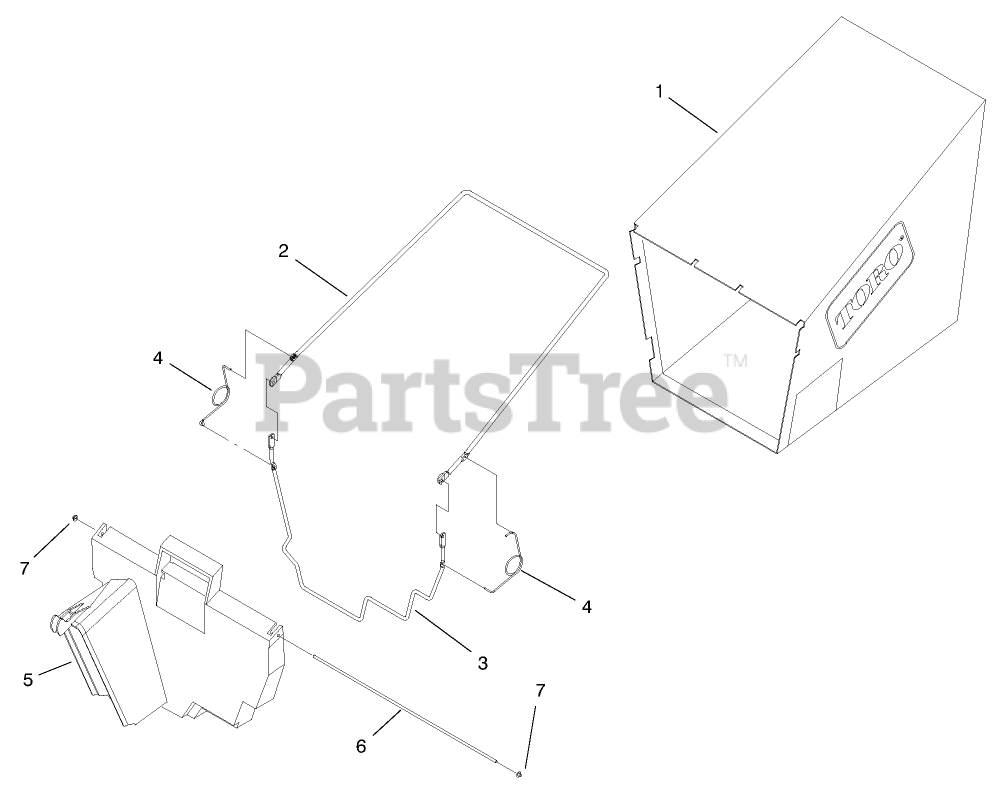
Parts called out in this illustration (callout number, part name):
1	BAG-GRASS
2	FRAME-BAG, UPPER
3	FRAME-BAG, LOWER
4	SPRING
5	DOOR-BAG
6	Hinge
7	NUT-PUSH
